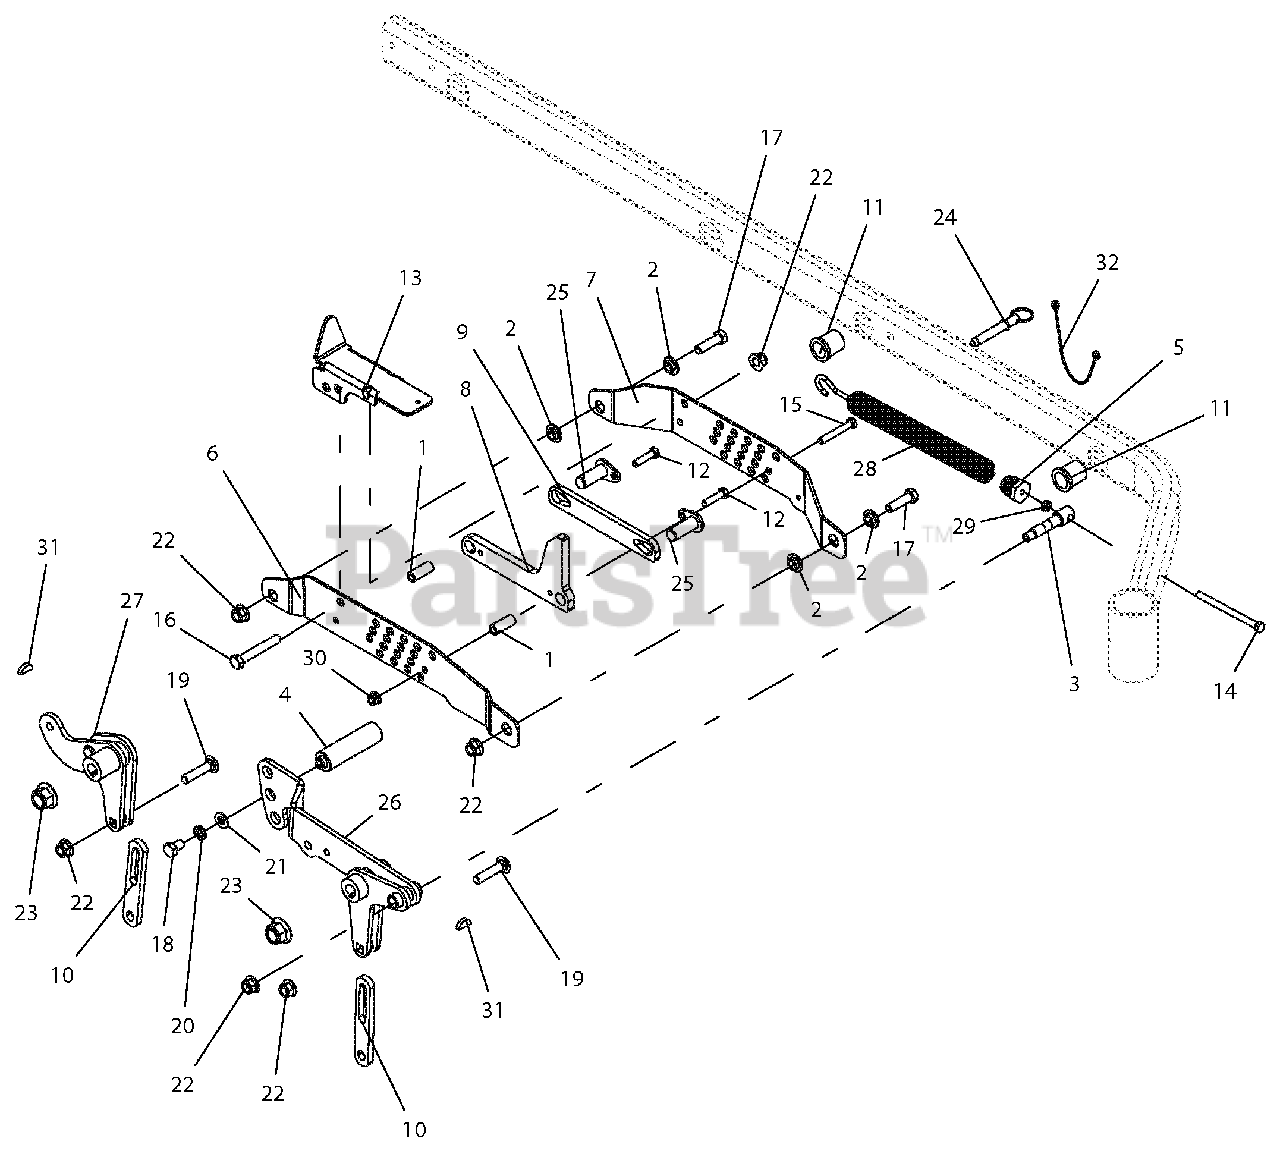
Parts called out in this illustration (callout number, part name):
1	SPACER, .375 X .625 X 1.54
2	BSHG, FLANGE .515X.750X.31X1.12
3	TRUNION, SPRG
4	PEDAL, LIFT
5	PLUG, SPRG
6	BRKT, RH INBOARD LIFT/CUT HEIGHT-BLACK
7	BRKT, RH INBOARD LIFT/CUT HEIGHT-BLACK
8	BRKT, HOC STOP-BLACK
9	BRKT, HOC STOP-BLACK
10	LINK, DECK LIFT - LONG
11	BSHG-FLG 1.00X1.25X1.5X1.5
12	BLT-HEX .38-16X1.50 GR5 YWZC EP30
13	WLDMT, MECHANICAL LOCK-UP-BLACK
14	BLT-HEX .38-16X5.00 GR5 YWZC
15	BLT-HEX .38-16X2.50 GR5 YWZC
16	BLT-HEX .50-13X3.25 GR5 YWZC
17	BLT-HEX .50-13X1.75 GR5 YWZC
18	BLT-HEX .50-13X.75 GR5 YWZC
19	BLT-RDHDSQNK .50-13X2.25 G5 Y
20	WSHR-LK .50X.125 REG YWZC
21	WSHR-FL-STL .505X1.00X.062 YWZC
22	NUT-LK-NYL-FLG .50-13 YWZC
23	NUT-LK-NYL-FLG .75-10 YWZC
24	PIN, .50 X 2.00 USABLE LG BALL
25	WLDMT, PIN
26	WLDMT, FRONT RH DECK LIFT ARM-BLACK
27	WLDMT, REAR RH DECK LIFT ARM-BLACK
28	SPRG, DECK LIFT
29	NUT, JAM .375-16 YWZC
30	NUT-LK-NYL-FLG .38-16 YWZC
31	KEY, WDRF .25 X 1.00 HRD #15
32	LANYARD, 12"
